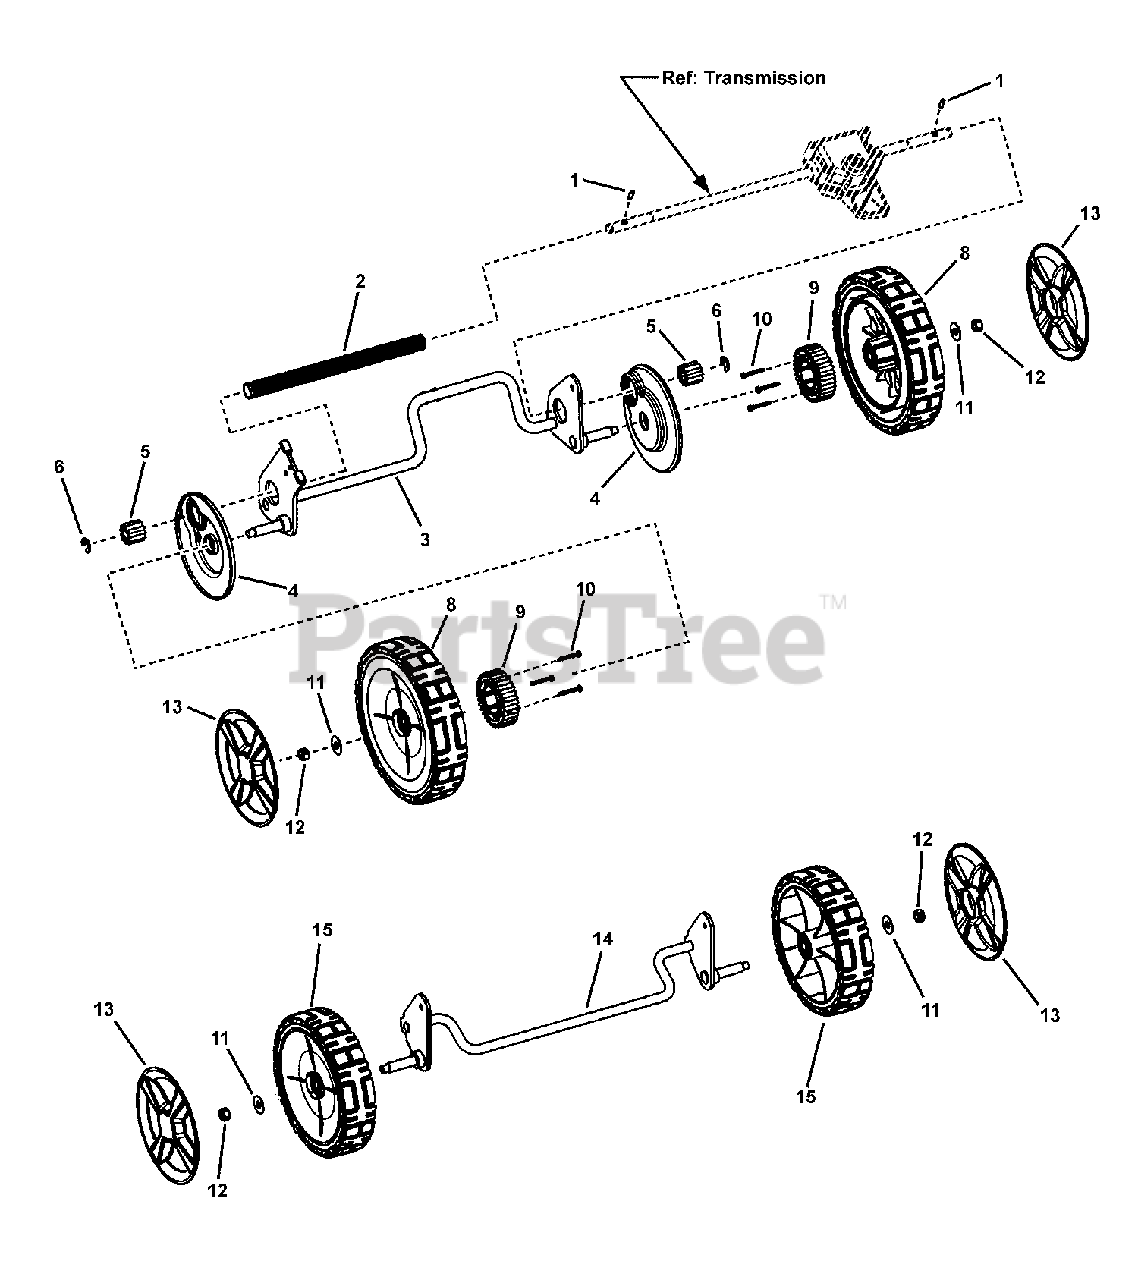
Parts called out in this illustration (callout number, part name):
1	PIN, Axle
2	SHIELD, Axle
3	WELDMENT, Rear Crossbar 21" WBM, RD, YZ
4	DUST SHIELD, 21" WBM, RD
5	GEAR, Pinion
6	RETAINING RING
8	ASSEMBLY, Wheel, 9 x 2 Idle, Snapper Tread, Charcoal Gray
9	GEAR, External Wheel
10	SCREW, #8 x 1-1/4 Hi-Lo, Hex Washer Self-Tap
11	WASHER, 1" OD x .387 ID, FLAT
12	NUT, 3/8-16 Hex Center Lock, YZ
13	HUBCAP, 8" & 9" Wheel Spoked- Snapper Cool Gray
14	WELDMENT, Front Crossbar 21" WBM, RD, YZ
15	ASSEMBLY, Wheel, 8 x 2 Idle, Snapper Tread, Charcoal Gray
